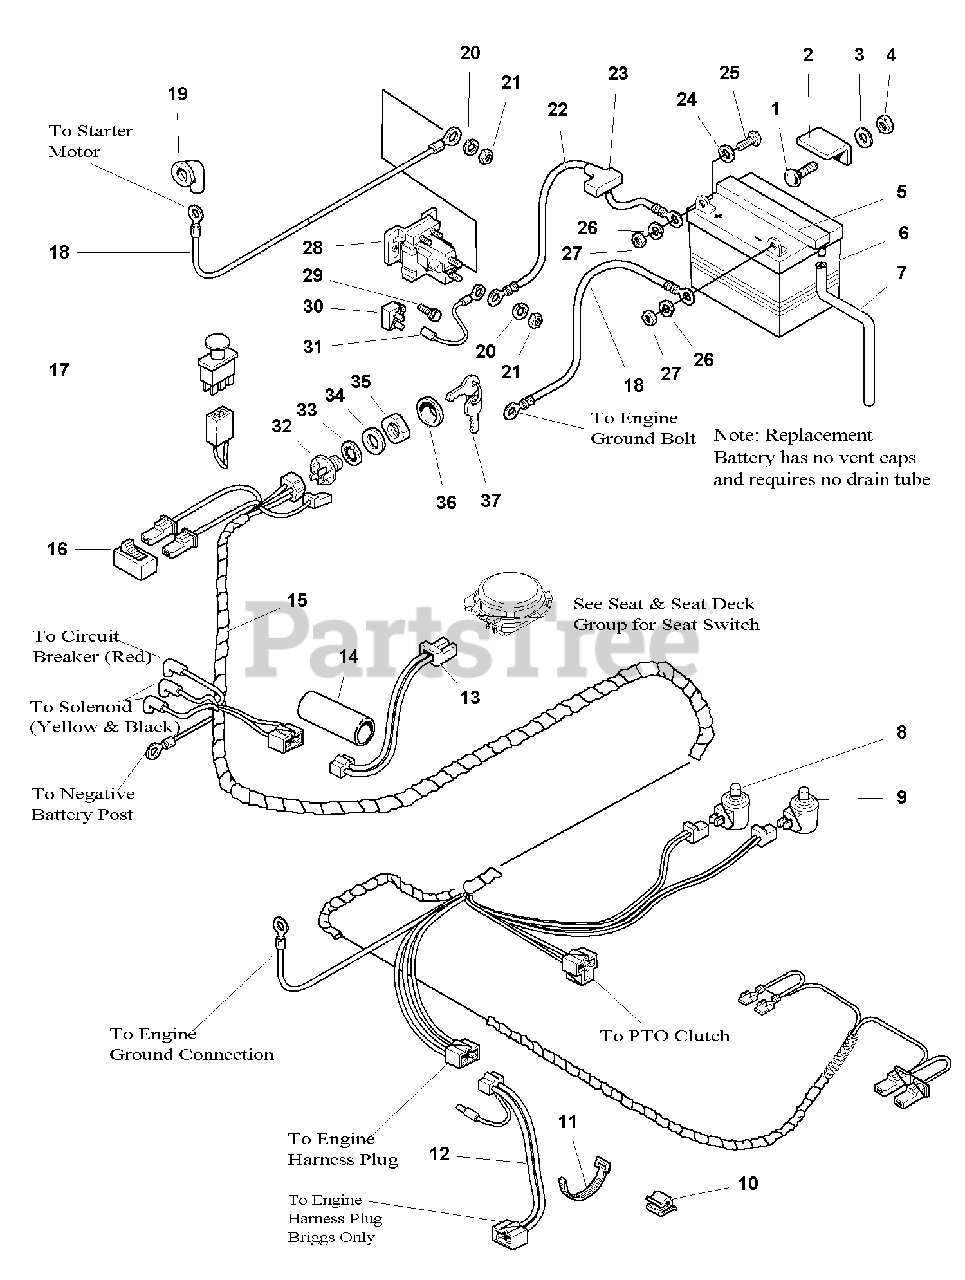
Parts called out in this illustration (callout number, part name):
1	CARRIAGE BOLT, 5/16-18 x 3/4
2	CLAMP, Battery
3	WASHER, Plain, 5/16
4	NUT, Hex Nylon Lock, 5/16-18
5	CAP, Vent, Battery
7	HOSE, Drain
8	SWITCH, Pedal, N.O., Black
9	SWITCH, Pedal, N.C., Gray
10	CLIP, Wire
12	WIRE ASSEMBLY, Harness To Engine (17 HP Briggs & Stration Only)
13	WIRE ASSEMBLY, Seat Switch
14	TUBE, Shrink
15	WIRING HARNESS, Main
16	SWITCH, Headlights
17	SWITCH, PTO
18	CABLE, (Solenoid to Starter & Battery to Ground)
19	BOOT, Insulator
20	LOCKWASHER, 5/16
21	NUT, Hex, 5/16-24 NF
22	CABLE, Battery, Positive
23	COVER, Terminal
24	WASHER, 1/4
25	CAPSCREW, Hex Head, 1/4-20 x 3/4
26	LOCKWASHER, 1/4
27	NUT, Hex, 1/4-20
28	SOLENOID
29	CAPSCREW, Taptite Hex Washer Head, 1/4-20 x 5/8
30	CIRCUIT BREAKER
31	WIRE ASSEMBLY
32	SWITCH, Ignition, Replacement Kit (Includes Ref. Nos. 33, 34, 35, 36 & 37)
33	WASHER, Lock, Internal Tooth, 5/8
34	WASHER, 5/8
35	NUT, Hex, Flange, 5/8-32
36	COVER, Ignition
37	KEY, Ignition
